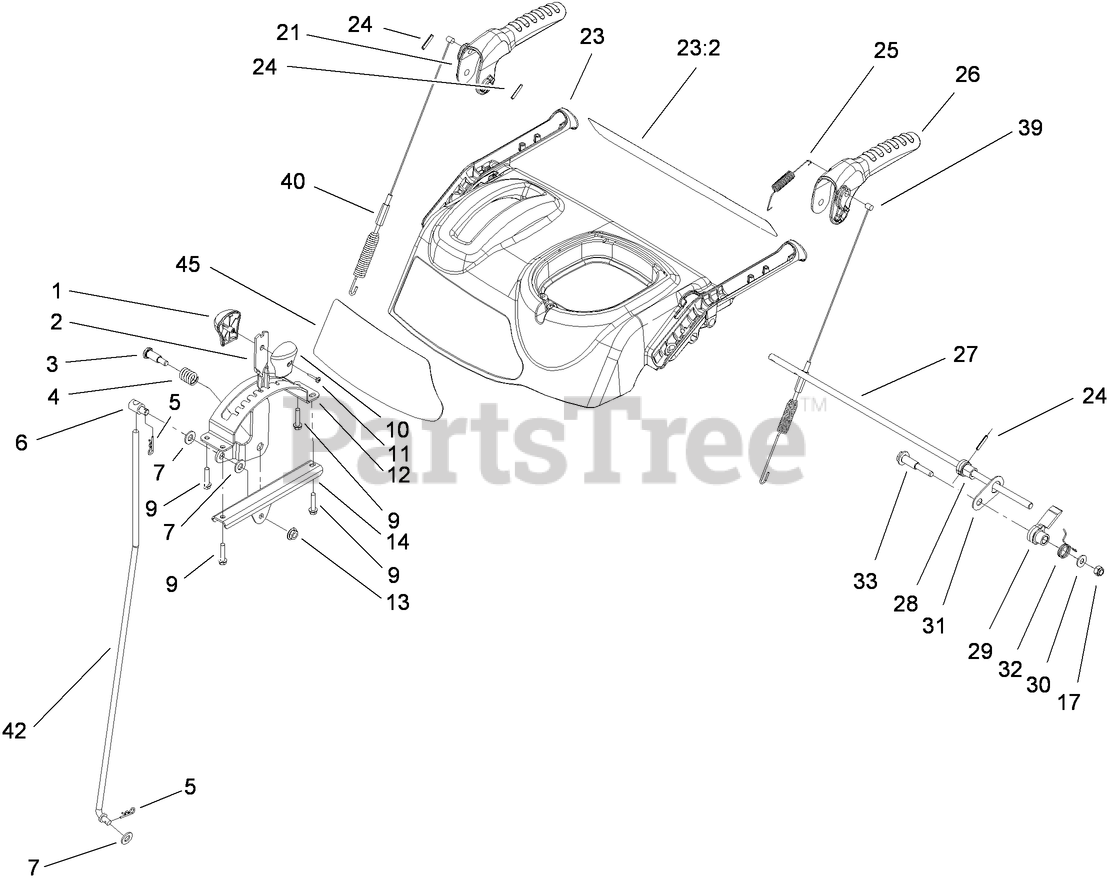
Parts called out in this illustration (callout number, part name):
1	KNOB-SHIFT, RH
2	SELECTOR-SPEED
3	SCREW-SHOULDER
6	TRUNNION-ROD
7	WASHER-FLAT
9	SCREW-PLASTITE
10	KNOB-SHIFT, LH
11	SCREW-PPH
12	GUIDE-SELECTOR, SPEED
13	NUT-HF
14	MOUNT-SELECTOR, SPEED
17	NUT-LOCK, NI
21	LEVER-AUGER
23	CONTROL PANEL ASM
23:2	DECAL-PANEL, CONTROL
24	PIN-SPRING
25	SPRING-TENSION
26	LEVER-TRACTION
27	ROD-LOCKOUT
28	CAM-LOCKOUT
29	LATCH-LOCKOUT
30	WASHER-FLAT
31	LINK-LOCKOUT
32	SPRING-TORSION
39	CABLE-TRACTION
40	CABLE-AUGER
45	DECAL-CONTROL PANEL
